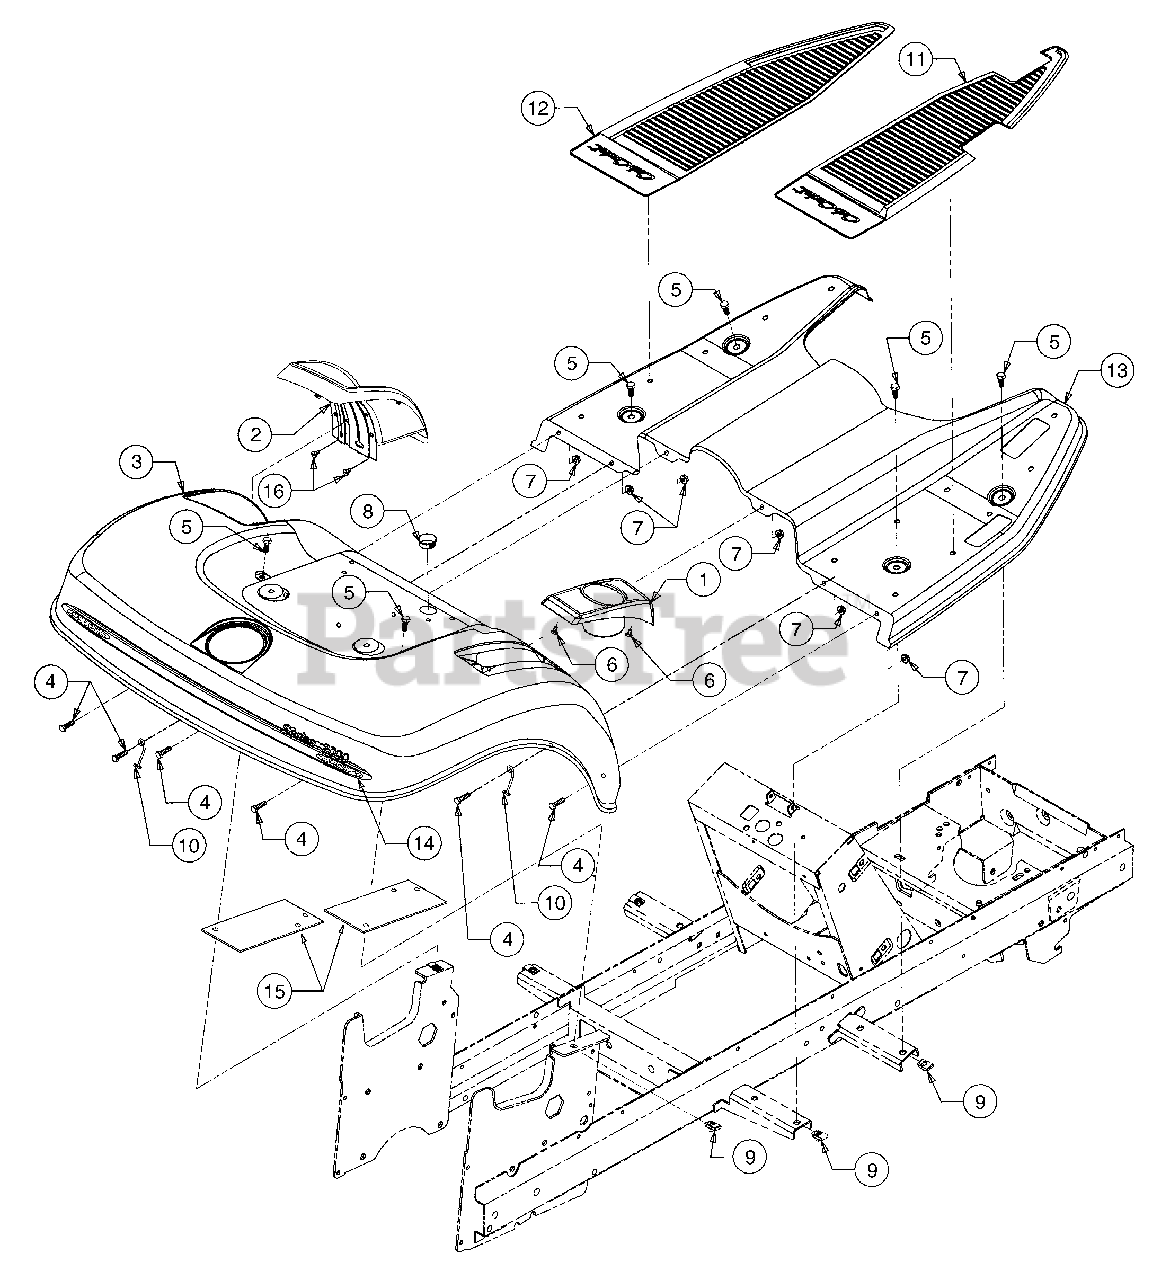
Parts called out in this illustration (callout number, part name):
1	Cup Holder
2	Cover, Implement Lift
4	Screw, Hex Cap, 1/4-20 x .62 GR5
5	Screw, Hex Wash Hd Tapp 5/16-18 x .750
6	Screw, Hex Tapp, #10 x .38 Lg
7	Nut, Hex Flange Lock, 1/4-20
8	Bushing, Snap, 7/8 ID
9	U-Nut, 5/16-18
10	Retainer, Hook
11	Pad, RH Foot
12	Pad, LH Foot
13	Running Board w/Graphic
14	Graphic, Rear Fender
15	Bracket, Fender Reinforcement
16	Screw, Hex Tapp, #10-16 x .5 Lg.
